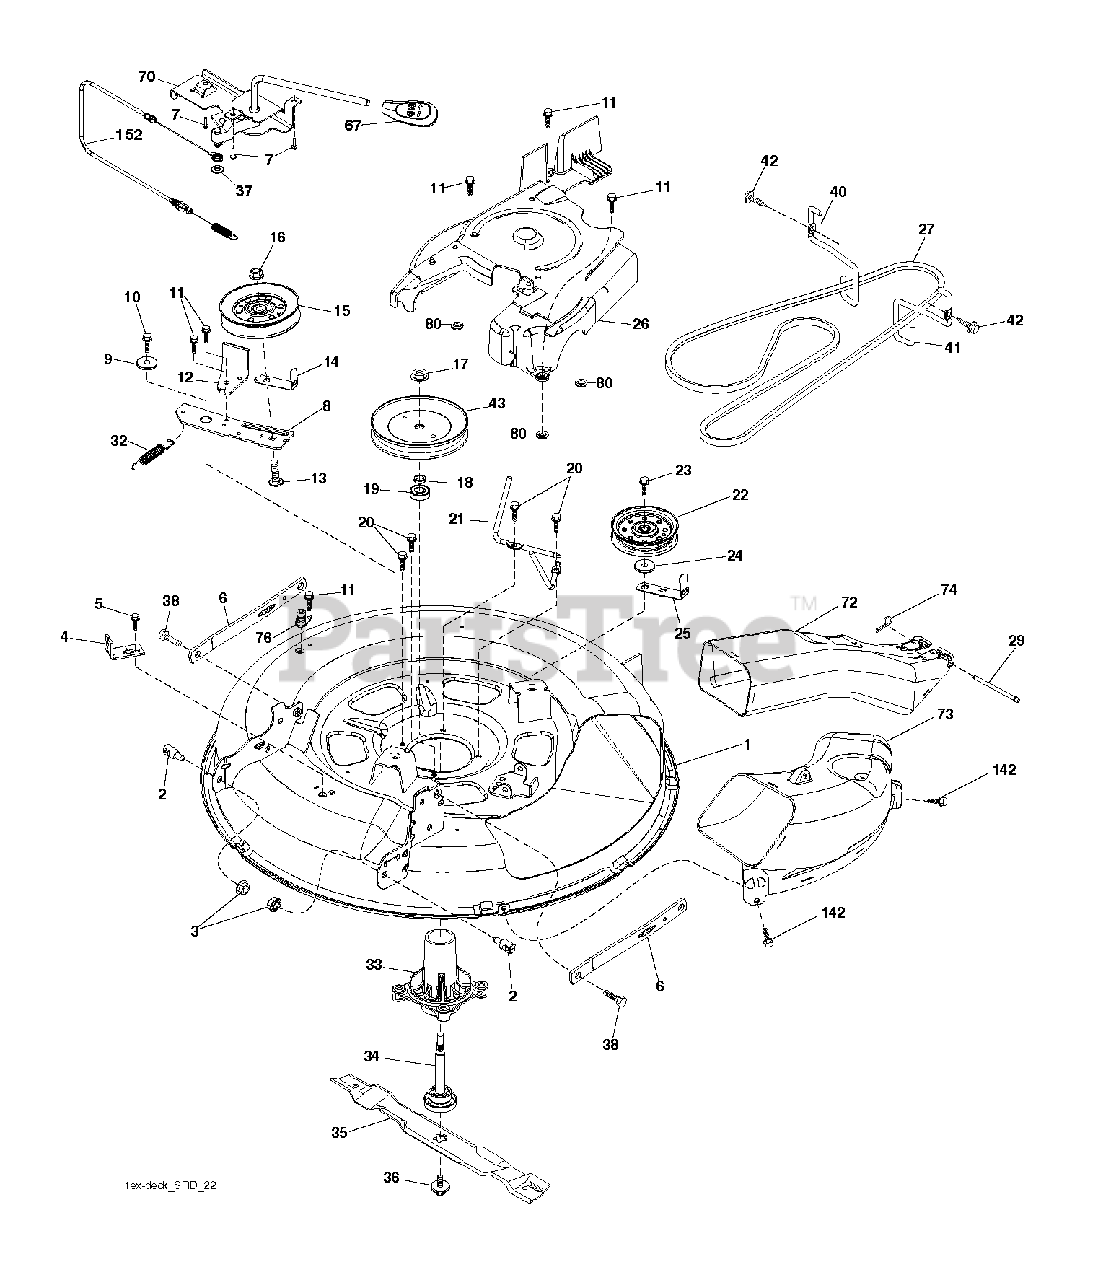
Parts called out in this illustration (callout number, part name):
1	DECK.WELDMENT.30"SRD.BLACK
2	STUD.FASTNER.W/ANTI-ROTATE
3	NUT LOCK HEX FLANGE 5/16-18
4	Clutch Cable Bracket
5	BOLT.5/16HEX.WHS.HD
6	ARMS.SUSP.MOWER.REAR.SRD
7	SCREW.#10 X 0.750.BOS THREAD
8	ARM.IDLER.30"SRD
9	SPACER.RETAINER
10	SCREW 3/8-16X1
11	SCREW.1/4-20X5/8
12	ARM BRAKE MOWER RH
13	BOLT.3/8-16X1.50
14	KEEPER, BELT IDLER
15	PULLEY.IDLER.4.25
16	NUT LOCK FLG 3/8-16 UNC
17	NUT.FLANGE.LOCK.TOP
18	WASHER.SPACER.MANDREL
20	SCREW, WASHER HEAD
21	KEEPER.BELT.MANDREL.30"
22	PULLEY.IDLER.FLAT.UNPLATED
23	SCREW LT
25	KEEPER.BELT.30"SRD
26	Mandrel Cover, 30" Deck
27	V-BELT.DRIVE.MOWER.30"
29	PIN.HINGE.30".SRD
32	SPRING RETURN
33	HOUSING MANDREL
34	SHAFT.ASM.MDRL.N/GREASE.38
35	BLADE.MOWER.BAGGING.30"
36	BOLT.WASHER.ASM.7/16-2
38	BOLT.SHOULDER
40	KEEPER.BELT.ENGINE.LH.LT.SRD
41	KEEPER.BELT.ENGINE.RH.LT.SRD
42	SCREW, 3/8-16X3/4
43	PULLEY, MANDREL 6.5 PD
70	CLUTCH.ASM.MANUAL.LT.PRED
72	CHUTE.UPPER.SRD.30R
73	Lower Chute, SRD 30R"
74	RETAINER-SPRNG RB
142	SCREW, 3/8-16X3/4
152	CABLE.CLUTCH.MANUAL.
